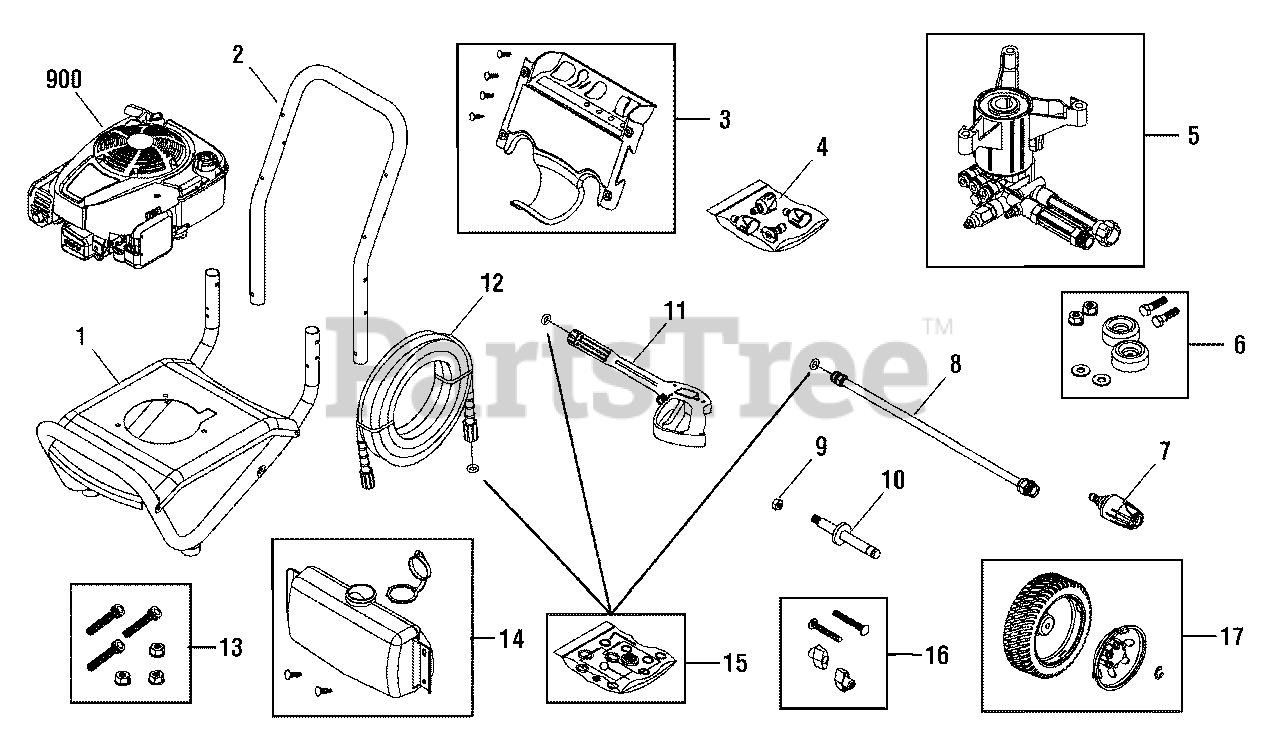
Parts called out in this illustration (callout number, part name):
4	KIT, QC Nozzles
6	MOUNT, Vibration
7	NOZZLE, Turbo
8	EXTENSION, QC
9	NUT
10	AXLE
11	GUN
13	KIT, Hardware, Pump Mounting
15	KIT, O-Ring
16	KIT, Hardware, Handle
17	KIT, Wheel
900	* ENGINE
